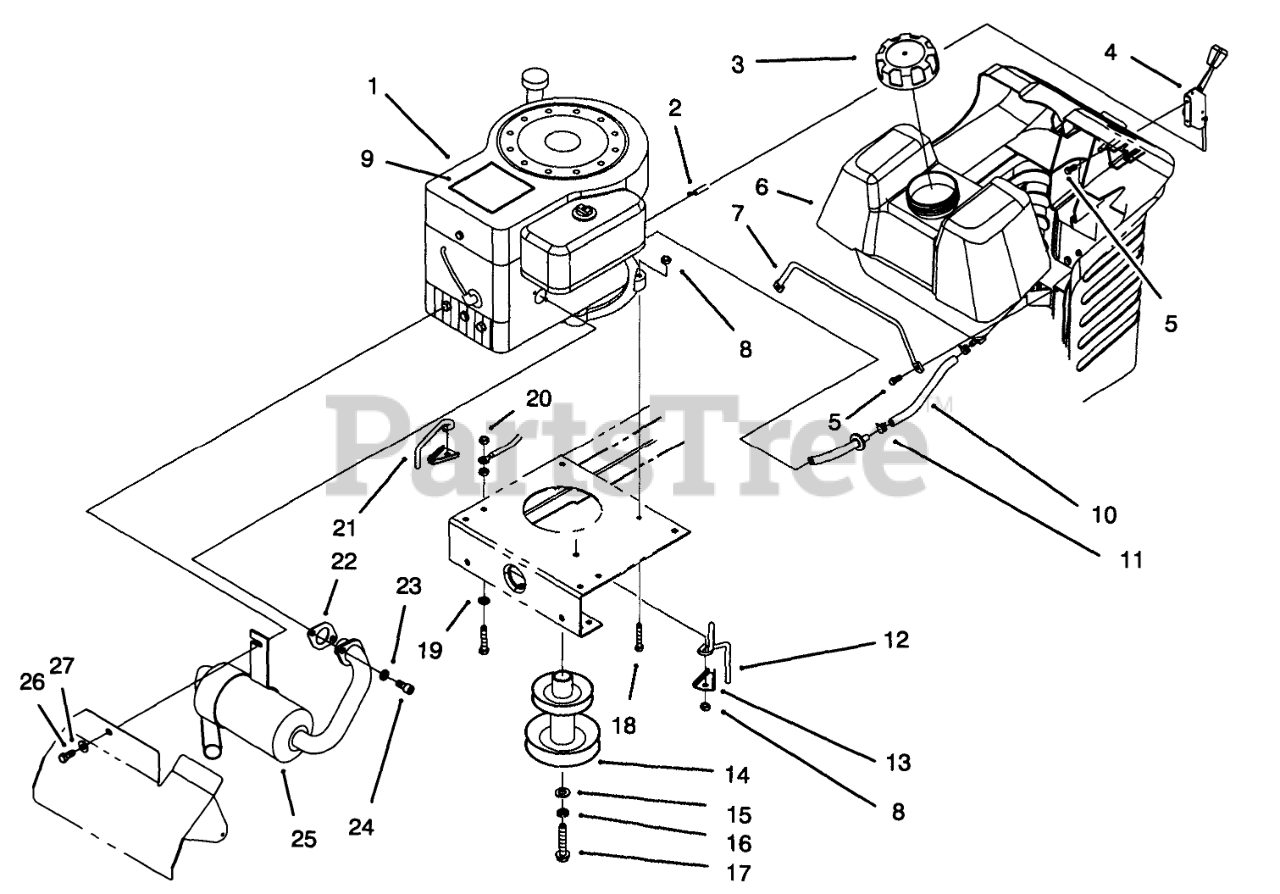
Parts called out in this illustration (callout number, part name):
1	Engine-12 H.P. (Model No. 71182 Only)
2	THROTTLE CABLE ASM
3	GAS CAP ASM
4	THROTTLE CONTROL ASM
5	SCREW-SPECIAL
6	GAS TANK ASM
7	GAS TANK ROD
8	NUT-LOCK, NI
9	DECAL - ENGINE
10	HOSE-FUEL
11	CLAMP-HOSE
12	GUIDE-BELT, LH
13	ANCHOR-GUIDE, BELT
14	PULLEY-ENGINE
15	WASHER-FLAT
16	WASHER-LOCK
17	SCREW-HH
18	SCREW-HH
19	WASHER-LOCK
20	NUT-KEPS
21	GUIDE-BELT, RH
22	GASKET-EXHAUST
23	WASHER-LOCK
24	SCREW-HSH
25	MUFFLER
26	SCREW-HH
27	WASHER-LOCK
